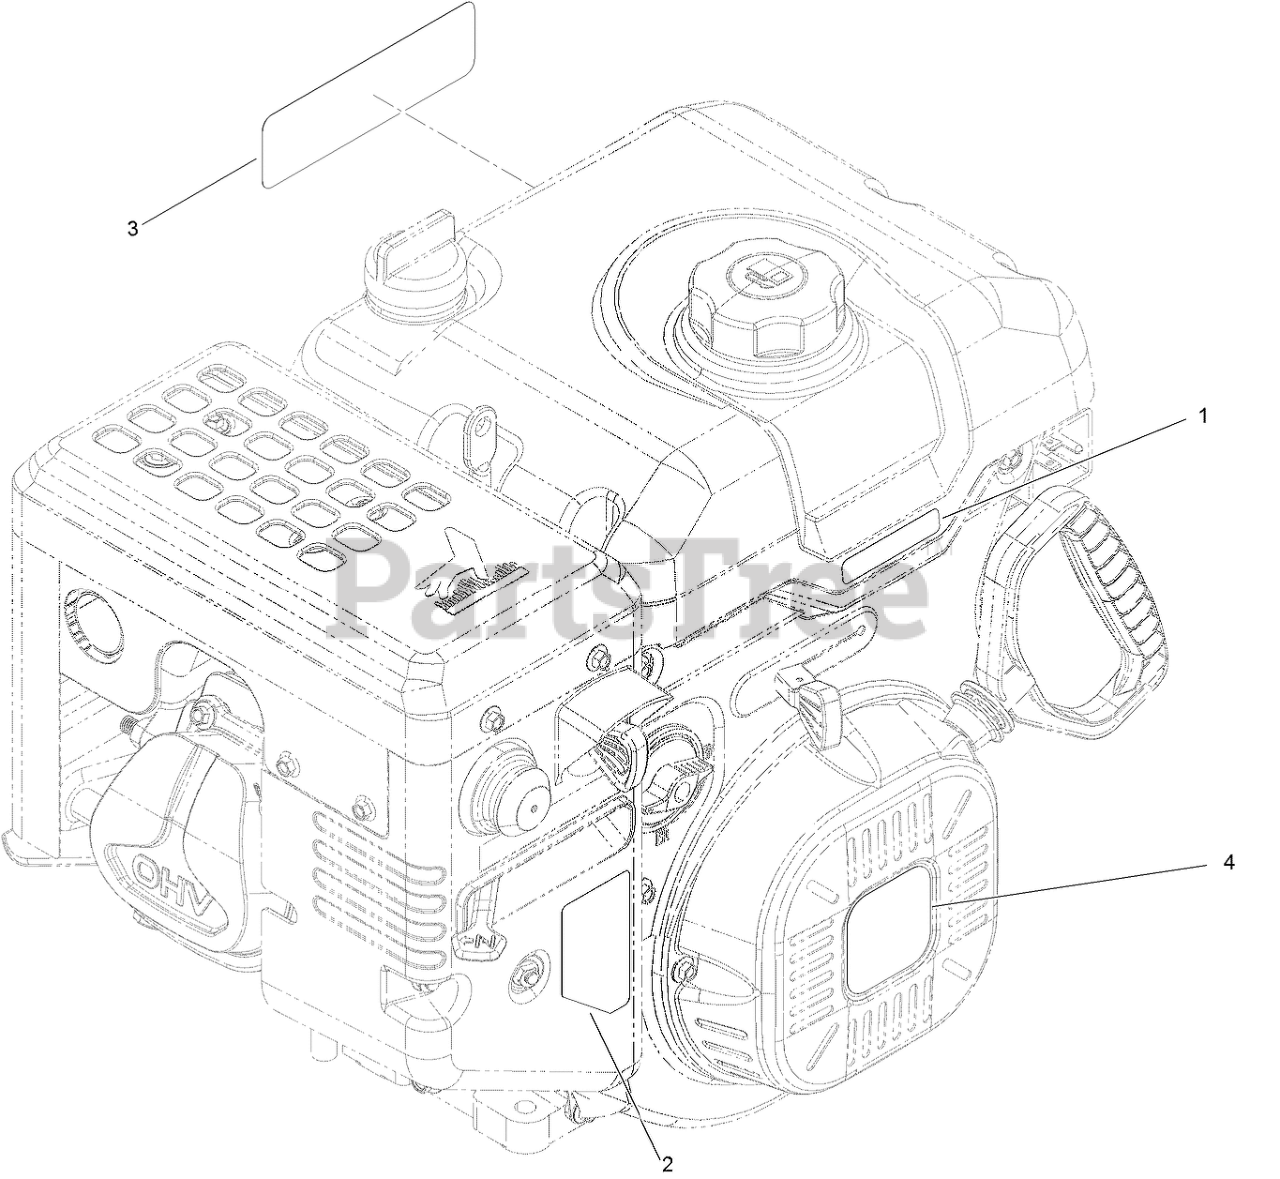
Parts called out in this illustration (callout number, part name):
1	DECAL-THROTTLE
2	DECAL-CONTROL, ENGINE
3	DECAL-ENGINE SERIES, G250
4	DECAL-RECOIL, G250
